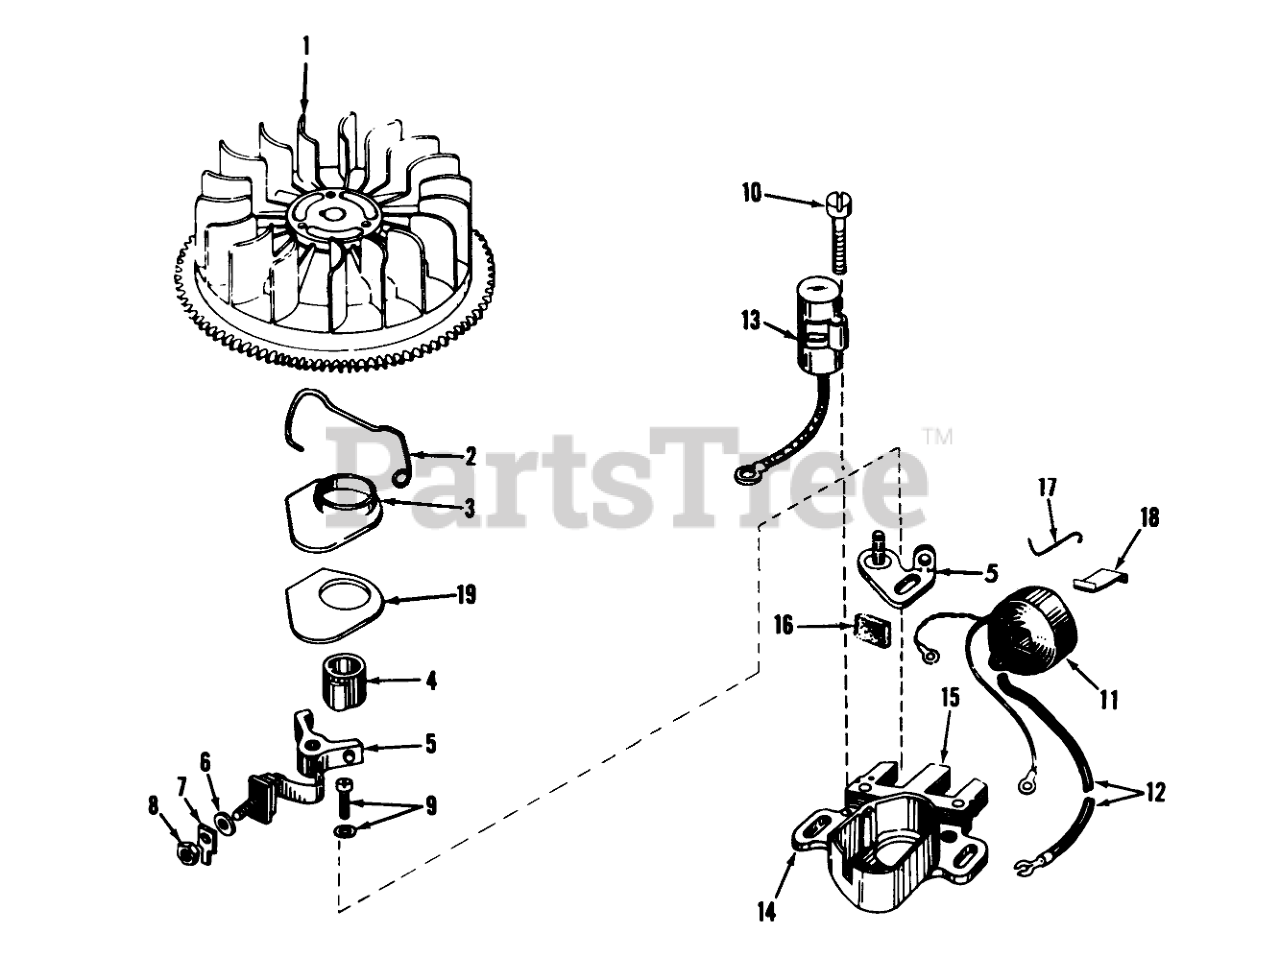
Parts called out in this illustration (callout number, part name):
1	Flywheel
2	Spring Breaker Box
3	Cover, Dust
4	Cam-Breaker
5	Breaker Assy.
7	Terminal
9	Breaker Screw
10	Condenser Screw
11	Coil Assy., (Incl. No.12)
12	Wire, Lead
13	Condenser
14	Core & Plate
15	Stator Assy., (Incl. Nos. 2, 3, 5 thru 14 & 16 thru 19)
16	Felt,Cam Wiper
17	Clip, Coil
18	Spring Coil Wedge
19	Gasket Dust
